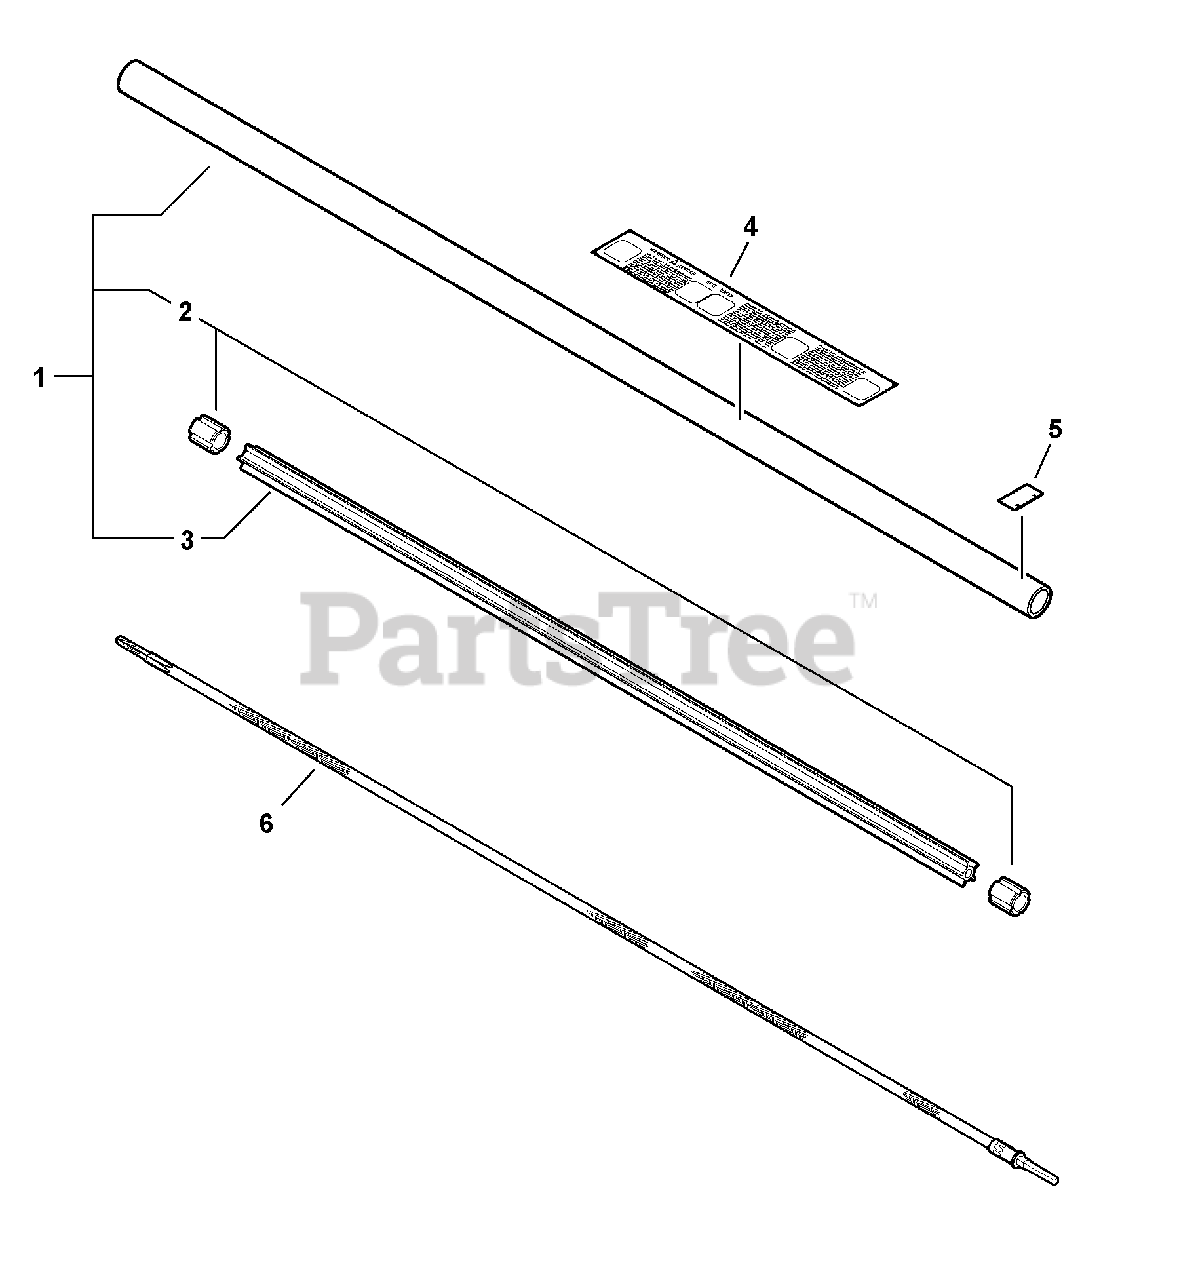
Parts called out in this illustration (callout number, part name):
1	MAIN PIPE ASSY
3	LINER - FLEXIBLE
4	DRIVESHAFT - FLEXIBLE
5	LABEL, CAUTION
6	LABEL - ALIGNMENT
